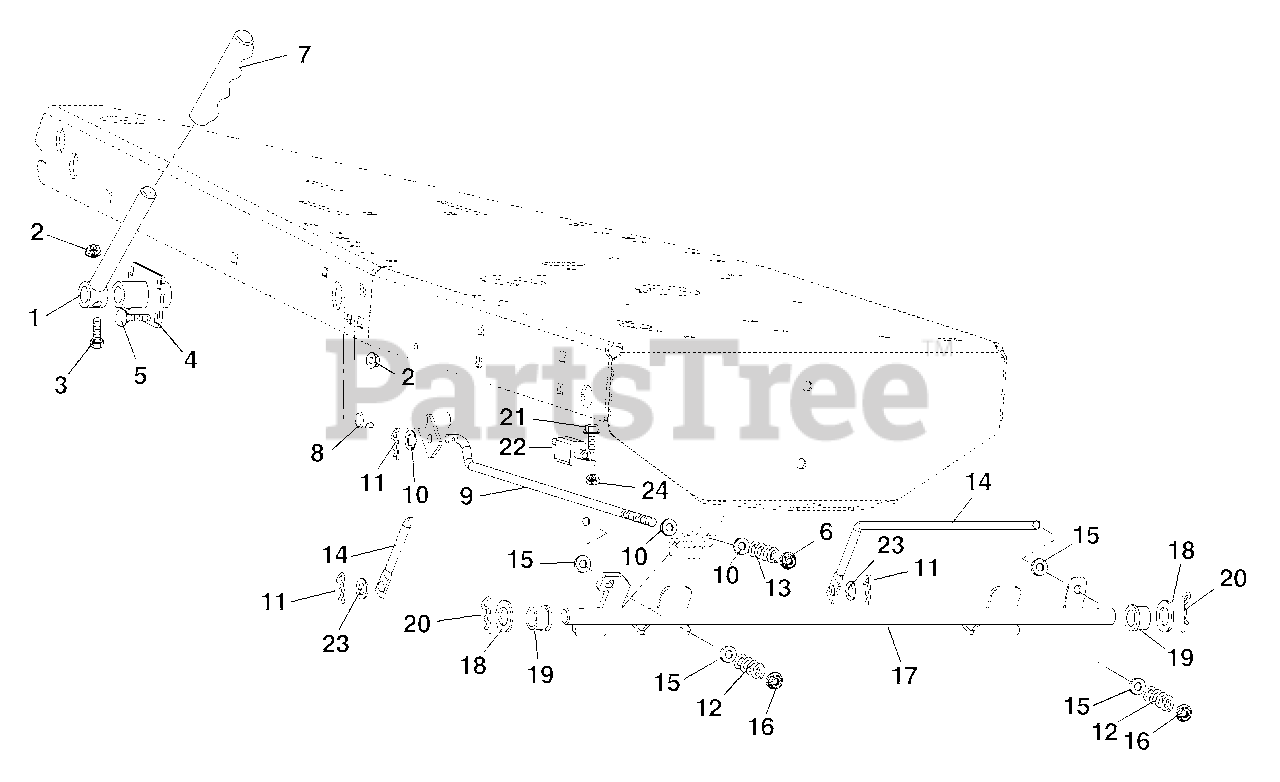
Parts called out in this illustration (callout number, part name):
1	Weldment, Handle
2	Nut, Locking Top Flange .31-18
3	Bolt, Hex .31-18 x 1.50 Grade 5
4	Weldment, Handle Pivot
5	Bolt, Round Head Square Neck .31-18 x .75 Grade 5
6	Nut, Locking Top Flange .38-16
8	Weldment, Pivot Arm
9	Rod, Arm Locking
10	Washer, Flat Steel .406 x .812 x .065
11	Pin, Hair
12	Spring, Compression .045 x .50 x 1.187
13	Spring, Compression .063 x .53 x 1.187
14	Rod, Brake Actuating
15	Washer, Flat Steel .344 x .688 x .065
16	Nut, Locking Top Flange .31-18
17	Shaft, Brake
18	Washer, Flat Steel .875 x 1.50 x .12
19	Bushing, Flange .63 x 1.00 x .625 Nylon
20	Pin, Spring Clip
21	Screw, Tapping 10-24 x .75 Hex Washer Head
22	Switch, Interlock NC
23	Washer, Flat Steel .406 x .812 x .065
24	Nut, Locking-Nylon 10-24 with Insert
